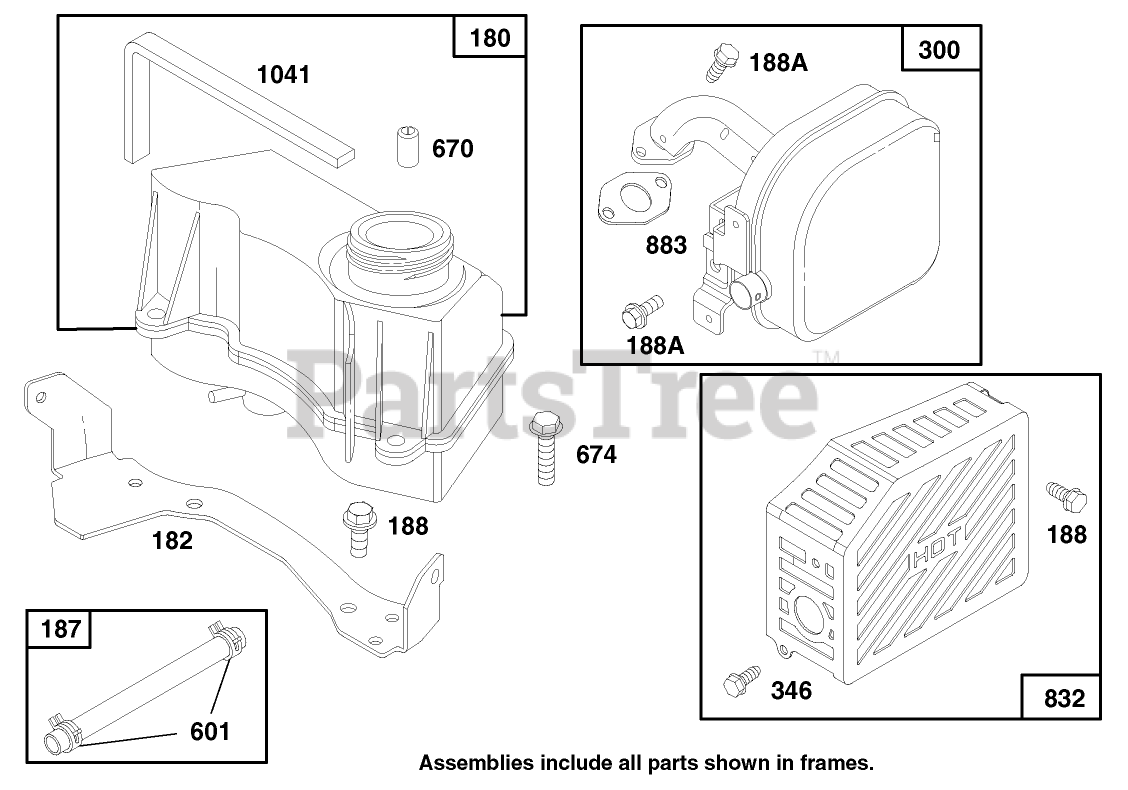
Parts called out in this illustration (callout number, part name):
180	TANK ASSY - FUEL
187	BRIGGS 296004
188	SCREW - HEX HEAD
300	MUFFLER - EXHAUST
670	SPACER
674	SCREW - HEX HEAD
